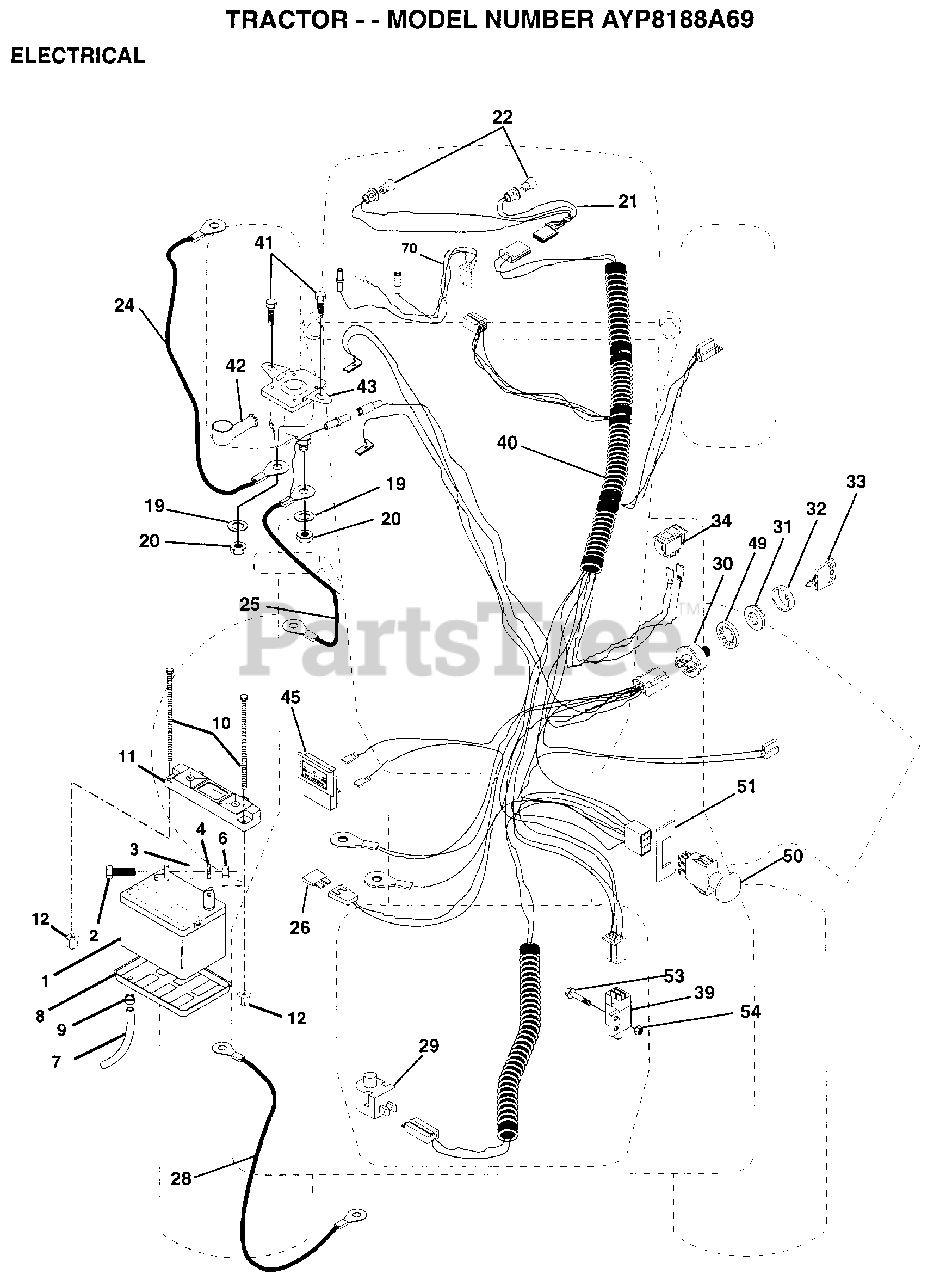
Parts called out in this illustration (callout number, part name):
2	BOLT LT
3	WASHER
4	LOCKWASHER
7	"DRAIN TU T, BATT"
8	"TRAY T, BATTERY"
9	HOSE CLAMP T
20	NUT
21	"HARNESS,LIGHT SOC"
22	HEADLAMP BULB
24	CABLE-BATTERY T
25	CABLE.6GA.12.5.
26	FUSE HYT
28	CABLE T
29	SWITCH SEAT
32	COVER KEY SWITCH
33	KEY MLD GEN DELTA
34	SWITCH LT
39	SWITCH INTERLOCKT
40	HARNESS.IGN.SRSGT
41	SCREW
45	AMMETER
49	LOCKWASHER
51	RING RETAIN PTO
53	SCREW
54	"NUT,KEPS"
70	HARNESS.ENG.VANII
